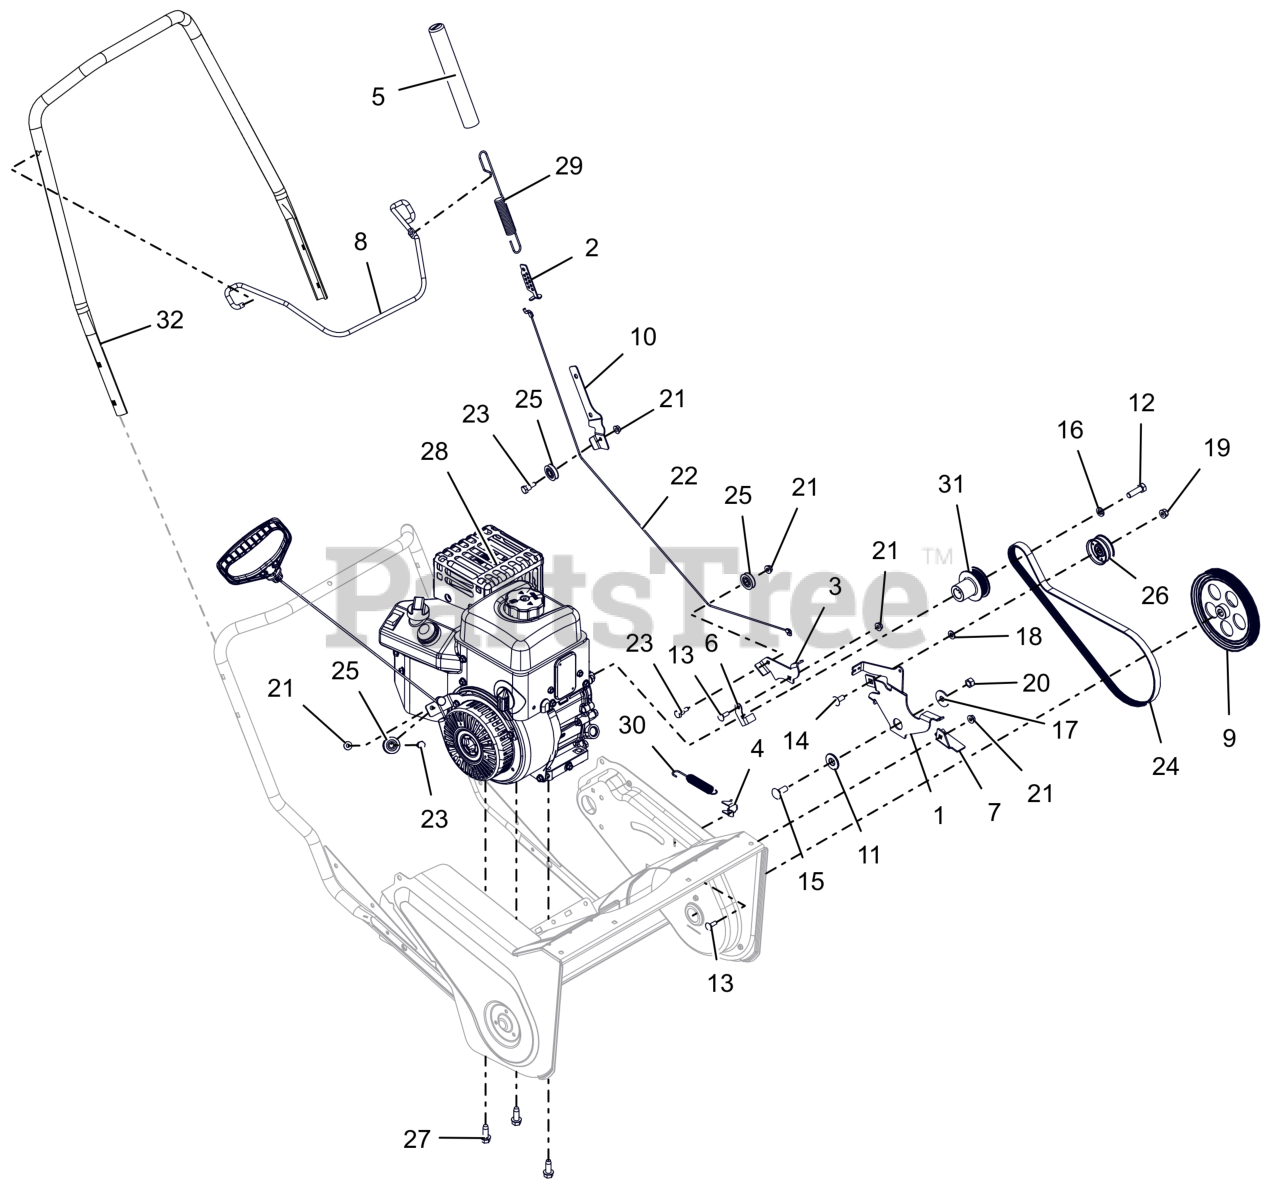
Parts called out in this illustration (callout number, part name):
1	ARM, IDLER /BRAKE
2	PLATE, CABLE ADJUSTMENT
3	BRKT, CABLE PULLEY
4	BRKT, SPRG
5	COVER, CABLE SPRING
6	FINGER, BELT
7	FINGER, BELT
8	BAIL, AUGER (BLACK)
9	PULLEY, POLY V-BELT J-6 W/HUB
10	MOUNT, CABLE PULLEY (ORANGE)
11	BSHG-FLG .555X.860X.220X1.250
12	BLT, HEX .38-24X1.25 G5 ZCC
13	BLT, RHSN .25-20X.750 G5 ZCC
14	BLT, RHSSN.31-18X.750 G5 ZCC
15	BLT, RHSN .38-16X1.00 G5 ZCC
16	WSHR,LK-REG .375X.094 ZCC
17	WSHR FL STL .406X1.25X.10ZC120
18	WSHR,FLT .323X.625X.062 ZCC
19	NUT,LK-CTR-FLG .31-18 GF ZCC
20	NUT-LK-CTR .38-16 ZC120
21	NUT-LK-TOP-FLG .250-20 GF ZCC
22	CABLE, AUGER
23	BOLT, SHLDR -.375 X .375 X .25-20
24	POLY V-BELT, J-6 RIBS
25	PULLEY, CABLE
26	IDLER, FLAT - 1.875"
27	SCR-TAP .38-16X1.00 HWH TR ZCC
28	Engine, AX208 LW RECOIL
29	SPRG, EXT .100X.740X8.175
30	SPRING, EXTENSION-SWIVEL
31	SHEAVE, ENGINE - 6J
32	HANDLEBAR, UPPPER - W/DECAL
